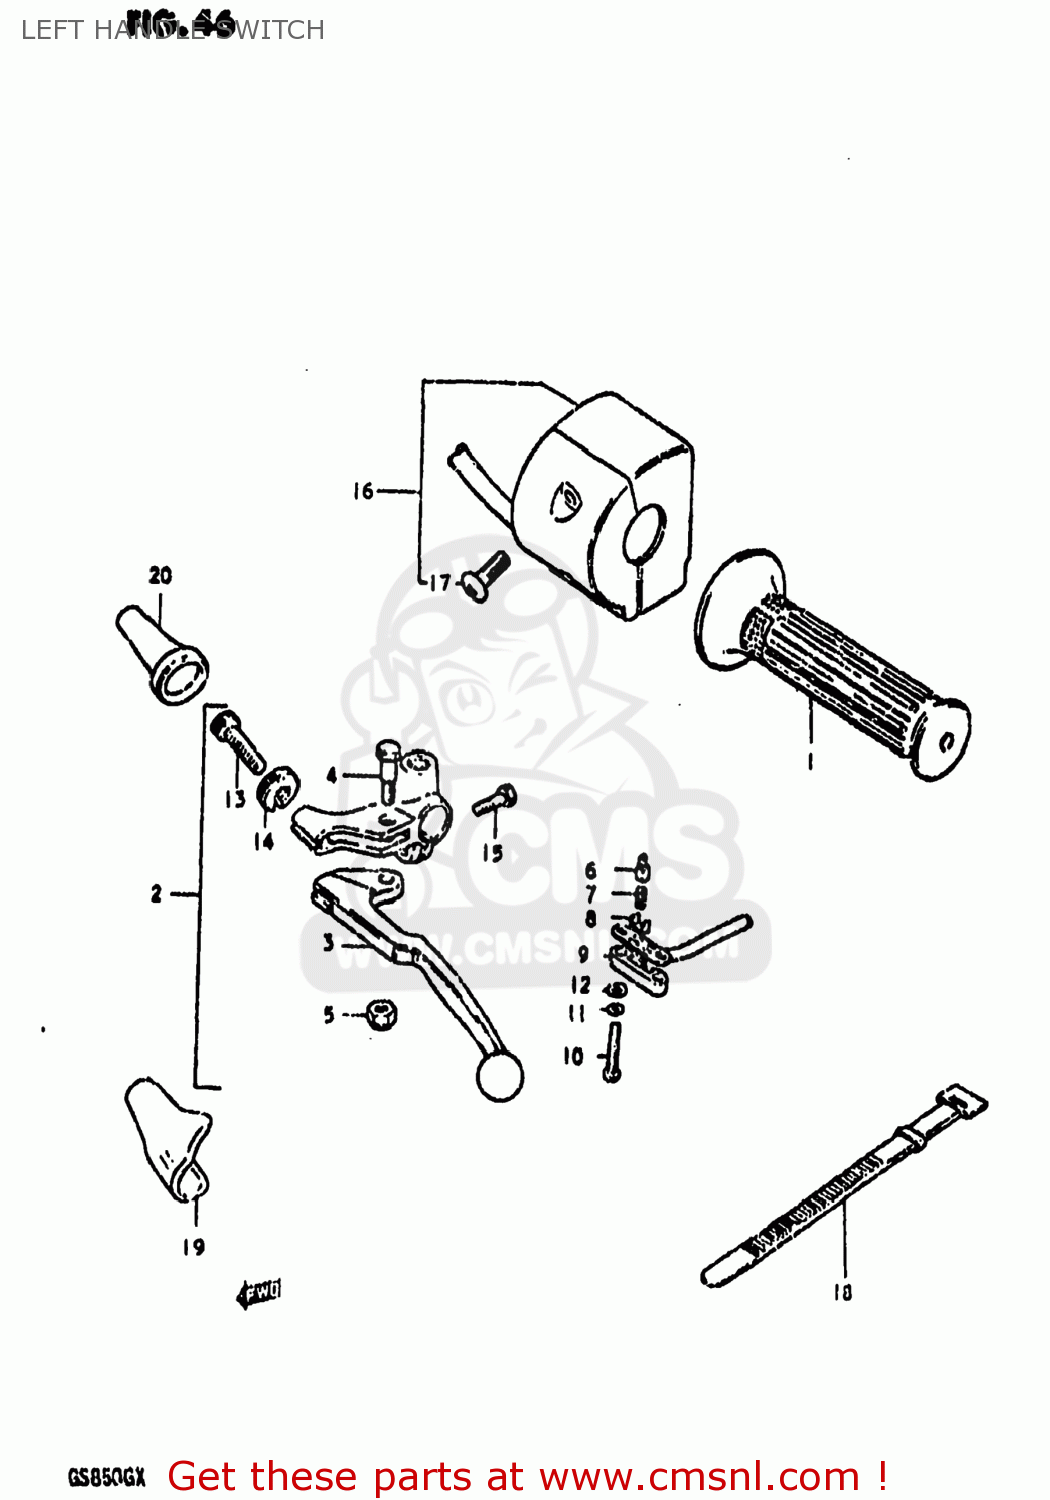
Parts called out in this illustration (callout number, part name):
1	GRIP,LEFT
2	LEVER ASSEMBLY
3	LEVER,CLUTCH
4	BOLT,LEVER
5	NUT 6MM
6	HOLDER
7	SPRING
8	PLATE
9	COVER,FR BK TERMINAL BASE
10	SCREW
11	LOCK WASHER
12	WASHER
13	ADJUSTER,CABLE
14	NUT,CABLE ADJUSTER
15	BOLT,CLUTCH LEVER HOLDER
16	SWITCH ASSEMBLY,HANDLE,LEFT
17	SCREW
18	CLAMP(L:120)
19	COVER,CLUTCH LEVER
20	BOOT,CLUTCH CABLE
